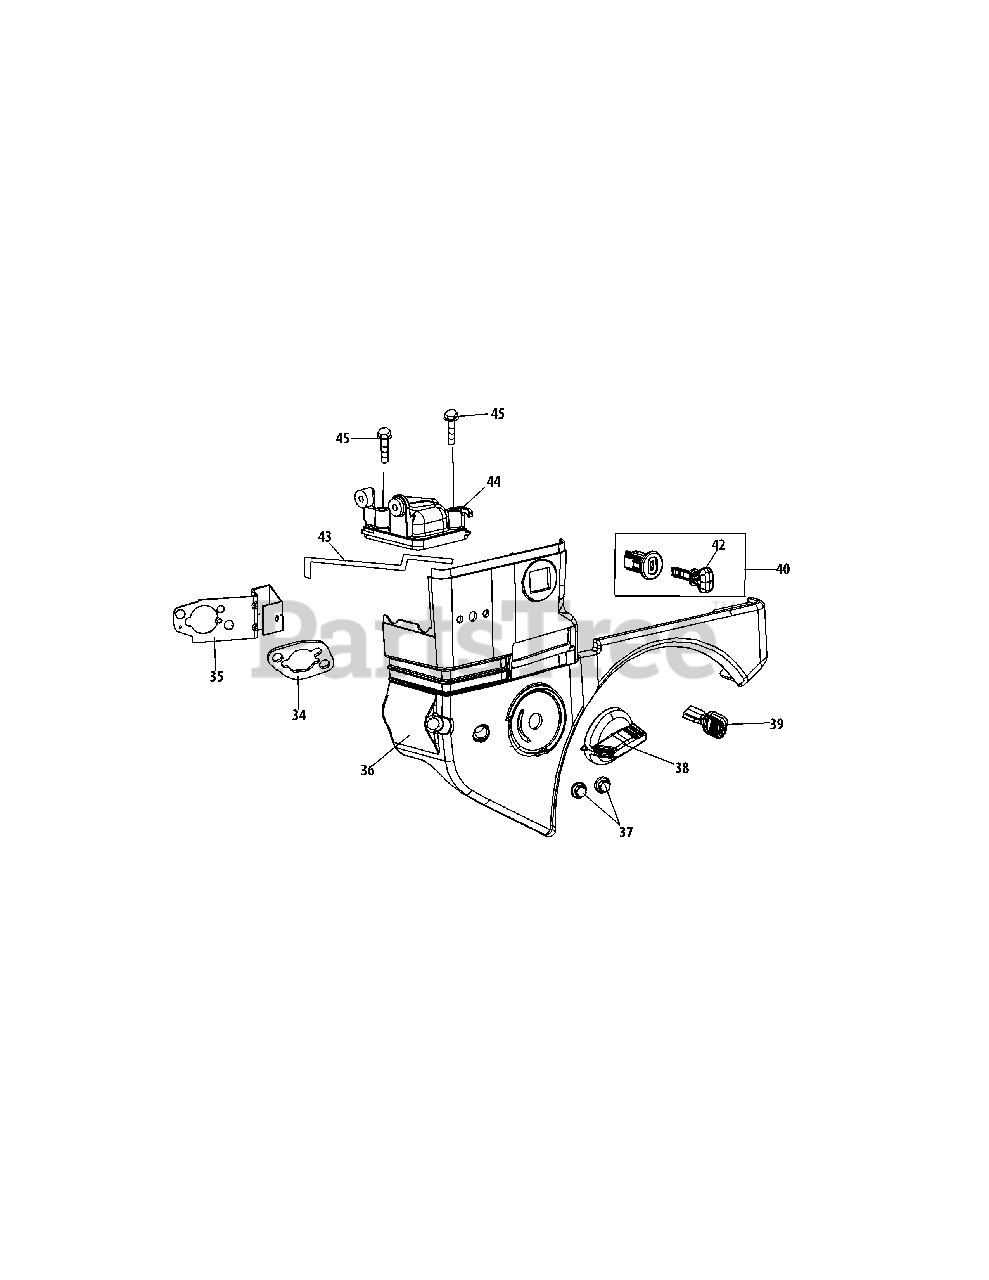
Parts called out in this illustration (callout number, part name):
34	Carburetor Gasket Plate
35	Choke Control Bracket
36	Engine Shroud
38	Choke Knob
39	Throttle Control Knob
40	Ignition Switch Assembly
43	Choke Push Rod
44	Heater Box
45	Bolt M6×25
